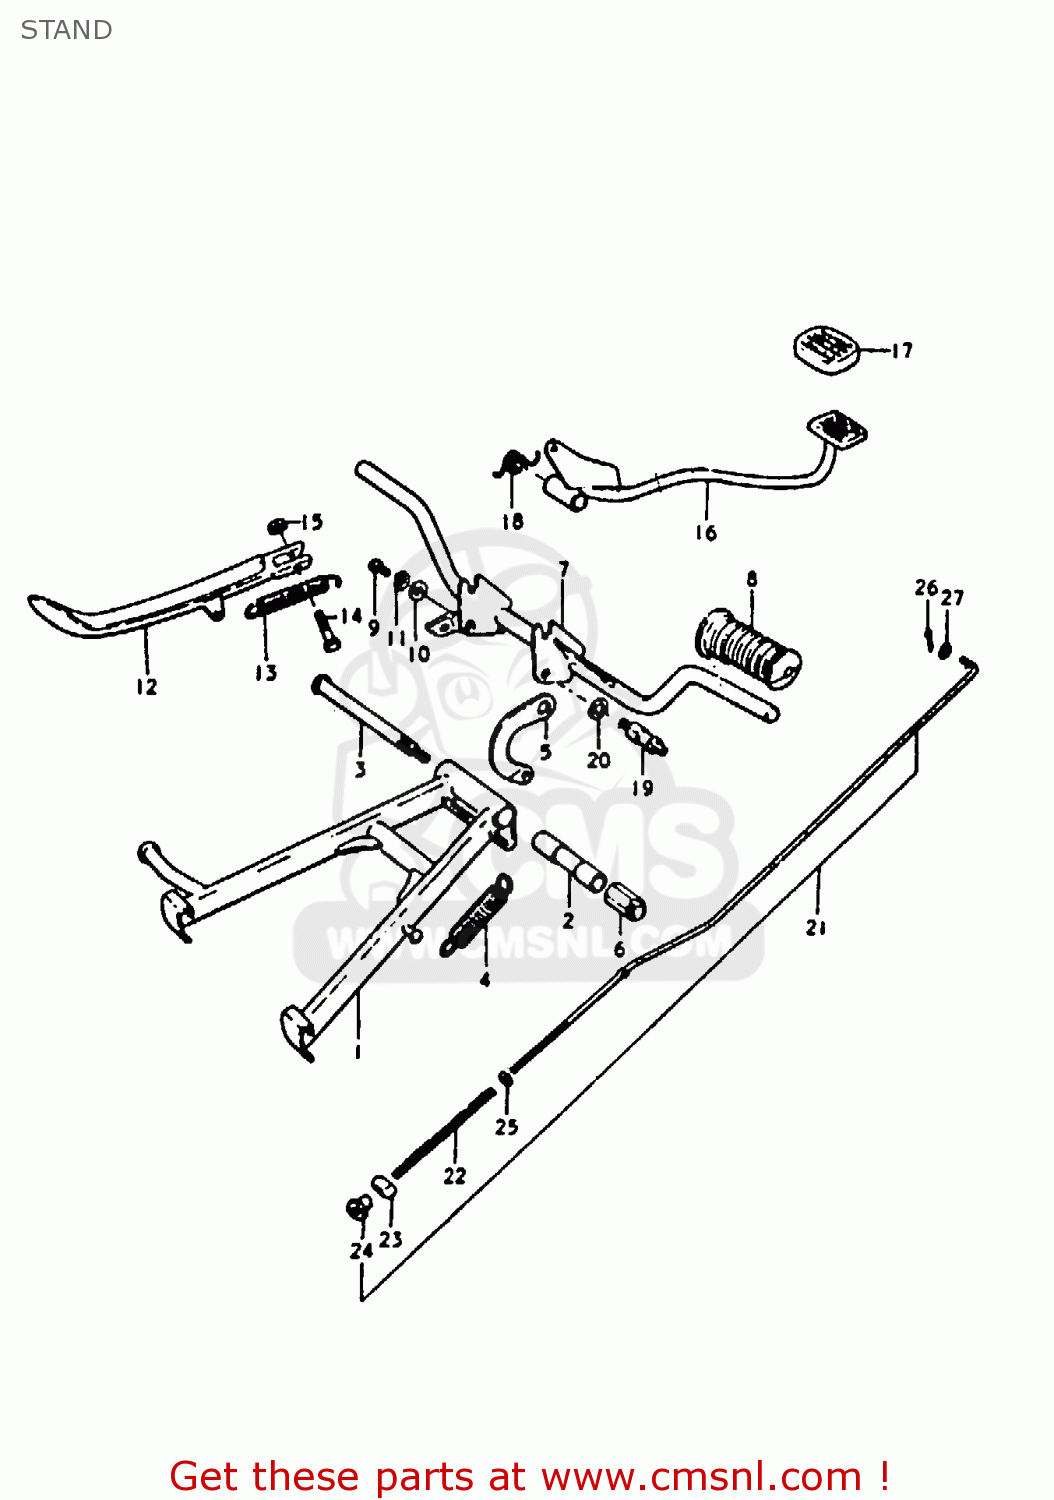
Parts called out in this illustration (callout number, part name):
1	STAND,CENTER
2	SPACER
3	BOLT,CENTER STAND
4	SPRING
5	HOOK,CENTER STAND SPRING
6	NUT,CTR STAND
7	BAR,FR FOOTREST
8	RUBBER,FRONT FOOTREST
9	BOLT
10	WASHER
11	LOCK WASHER
12	STAND,SIDE
13	SPRING
14	BOLT
15	NUT
16	PEDAL,BRAKE
18	SPRING
19	STOPPER,BRAKE PEDAL
20	WASHER
21	ROD ASSY,RR BRAKE
22	SPRING
23	PIN(11X18)
24	NUT
25	WASHER
26	PIN 20X20
27	WASHER
